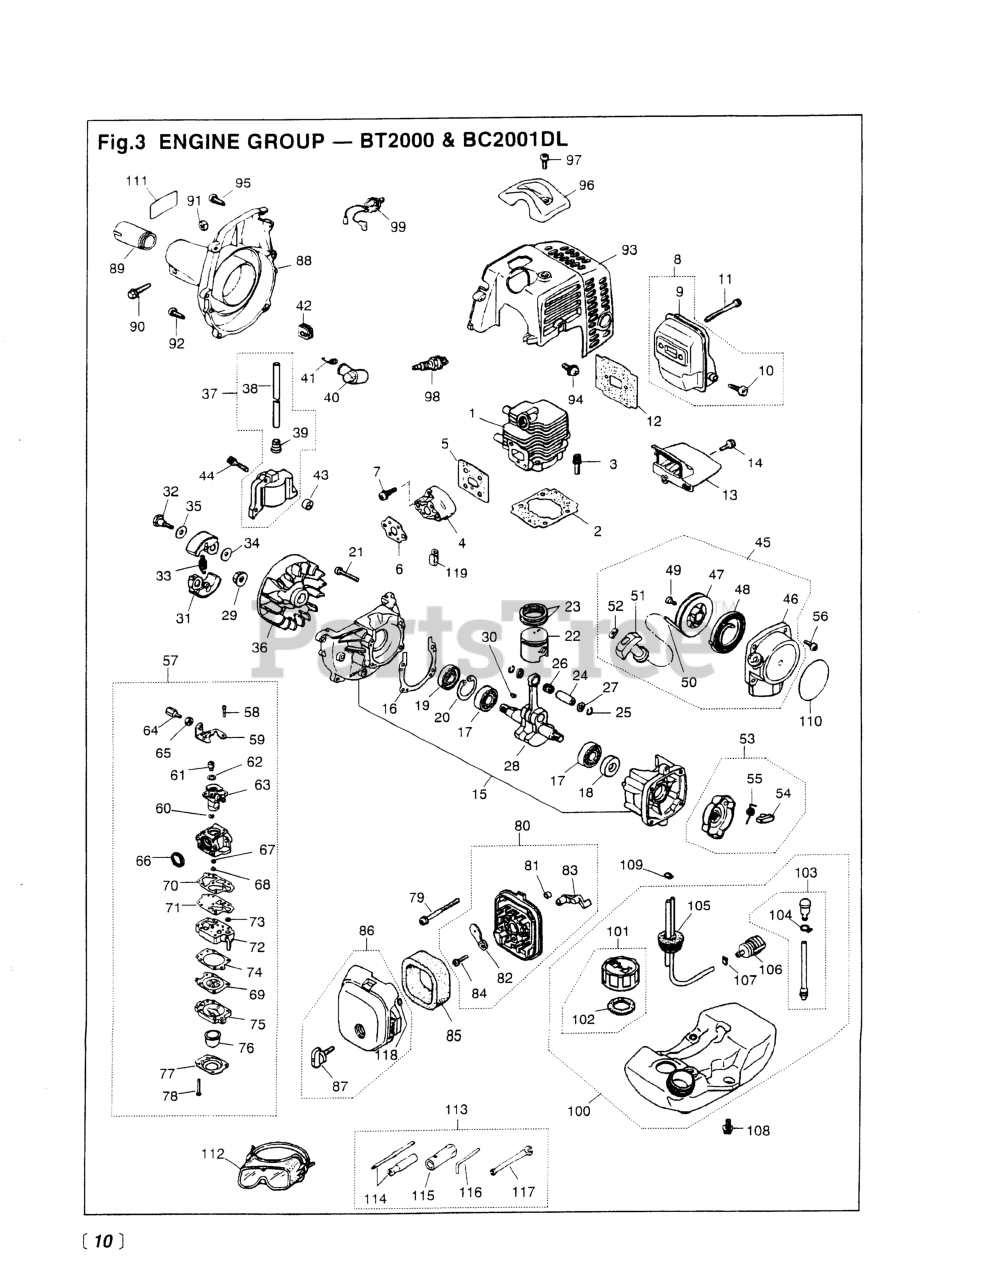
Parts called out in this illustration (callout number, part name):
1	CYLINDER
3	BOLT, M5 X 22
7	SCREW, M5X20 (RPLS.1400-75510)
9	MUFFLER ASSY (USE 5913-15100)
10	ARRESTER (RPLS 5850-15140)
11	BOLT, M5 x 50
12	GASKET, MUFFLER
14	SCREW, M4 X 16
15	CRANKCASE
17	BEARING
18	SEAL, OIL (RPLS 1100-21210)
19	SEAL, OIL (RPLS 1140-21220)
20	RING, SNAP, M28 x 1.2
21	BOLT, M5 X 30
22	PISTON (REPLACES 1140-41110)
23	RING, PISTON (RPLS 1850-41210)
24	PIN, PISTON 5x8x26
25	RING, SNAP (RPLS 1101-41320)
27	WASHER
28	CRANKSHAFT (RPLS 1850-42000)
30	KEY
32	BOLT
33	SPRING, CLUTCH (RPLS-51220)
34	WASHER, FLAT (USE 182303)
38	CORD
39	CAP
41	SPRING
42	GROMMET
43	SPACER (RPLS -71260)
44	BOLT
45	RECOIL ASSEMBLY
46	CASE
47	REEL
48	SPRING, SPIRAL
49	SCREW (RPLS -75150)
51	KNOB
52	PLATE, STOPPER
53	PULLEY ASSY (RPLS -75210)
54	RATCHET (RPLS 1850-75220)
55	SPRING, RETURN
56	SCREW, M4 X 16
57	CARBURETOR (RPLS-81000)
58	SCREW
60	RING
61	SWIVEL
62	WASHER
63	VALVE ASSY
64	SCREW, CABLE ADJUSTER
65	NUT, CABLE ADJUSTER
66	RING, PACKING
67	RING, O
68	JET
69	DIAPHRAGM (USE 4810-81260)
70	GASKET, PUMP
71	DIAPHRAGM
72	BODY, PUMP
74	GASKET, DIAPHRAGM
75	BODY, PURGE
76	PUMP, PRIMING
77	COVER, PUMP
78	SCREW
79	SCREW, M5 X 55
81	SLEEVE
82	PLATE, CHOKE (RPLS-82130)
83	LEVER, CHOKE
84	SCREW (REPLACES 50030272)
85	ELEMENT
88	HOUSING COMPLETE
90	BOLT, M6x35 (RPLS -50635)
91	NUT, M6 X 5
92	SCREW, M5X20 (RPLS.1400-75510)
94	SCREW, M5 x 12
95	SCREW, HOUSING
96	GUARD, PLUG
97	SCREW,M5 X 14 (RPLS 1400-15510
99	SWITCH
101	CAP (RPLS -85200)
102	PACKING
104	CLIP
105	PIPE COMPLETE
106	FILTER (RPLS 1850-85300)
107	CLIP (REPLACES 2841-31280)
108	SCREW
109	CLIP
111	LABEL, FAN COVER
113	TOOL SET
114	SCREWDRIVER
115	SOCKET, HEX, 3/4
116	BAR
117	SPANNER, 8 X 10 (RPLS 2540- )
119	CLAMP
